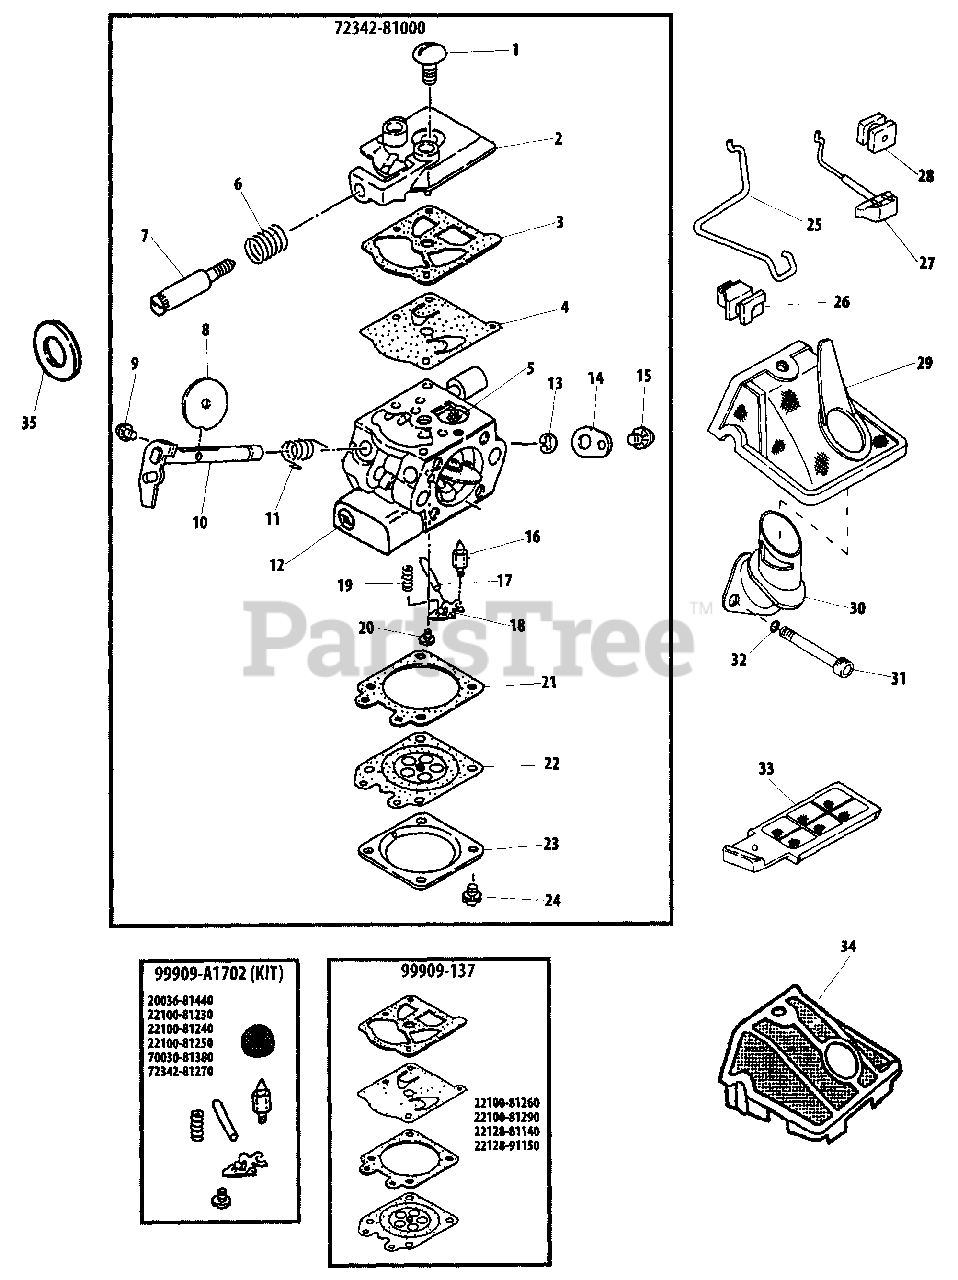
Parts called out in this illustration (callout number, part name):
1	SCREW
2	COVER ASSY, PUMP
3	GASKET, PUMP
4	DIAPHRAGM, PUMP
5	SCREEN, FUEL INLET
6	SPRING, IDLE ADJUST
7	SCREW, IDLE ADJUST
8	VALVE, THROTTLE
9	SCREW ASSY
10	SHAFT, THROTTLE
11	SPRING, THROTTLE RETURN
12	LIMITER CAP, L SPEED
13	E-RING
14	LEVER, THROTTLE
15	SCREW
16	VALVE, INLET NEEDLE
17	PIN, METERING LEVER
18	LEVER, METERING
19	SPRING, METERING LEVER
20	SCREW, METERING LEVER PIN
21	GASKET, METERING DIAPHRAGM
22	DIAPHRAGM, METERING
23	COVER, METERING DIAPHRAGM
24	SCREW
25	ROD, THROTTLE
26	GROMMET, ROD
27	ROD, CHOKE
28	GROMMET, CHOKE
29	FILTER, AIR
30	ELBOW
31	BOLT, ADHESIVE M5×40
32	WASHER, FLAT 5.5×10×0.8
33	FILTER, AIR
34	FILTER, FLOCKED AIR
35	SEAL, COLLAR
72342-81000	CARBURETOR
99909-137	DIAPHRAGM/GASKET KIT
99909-A1702	REPAIR KIT
